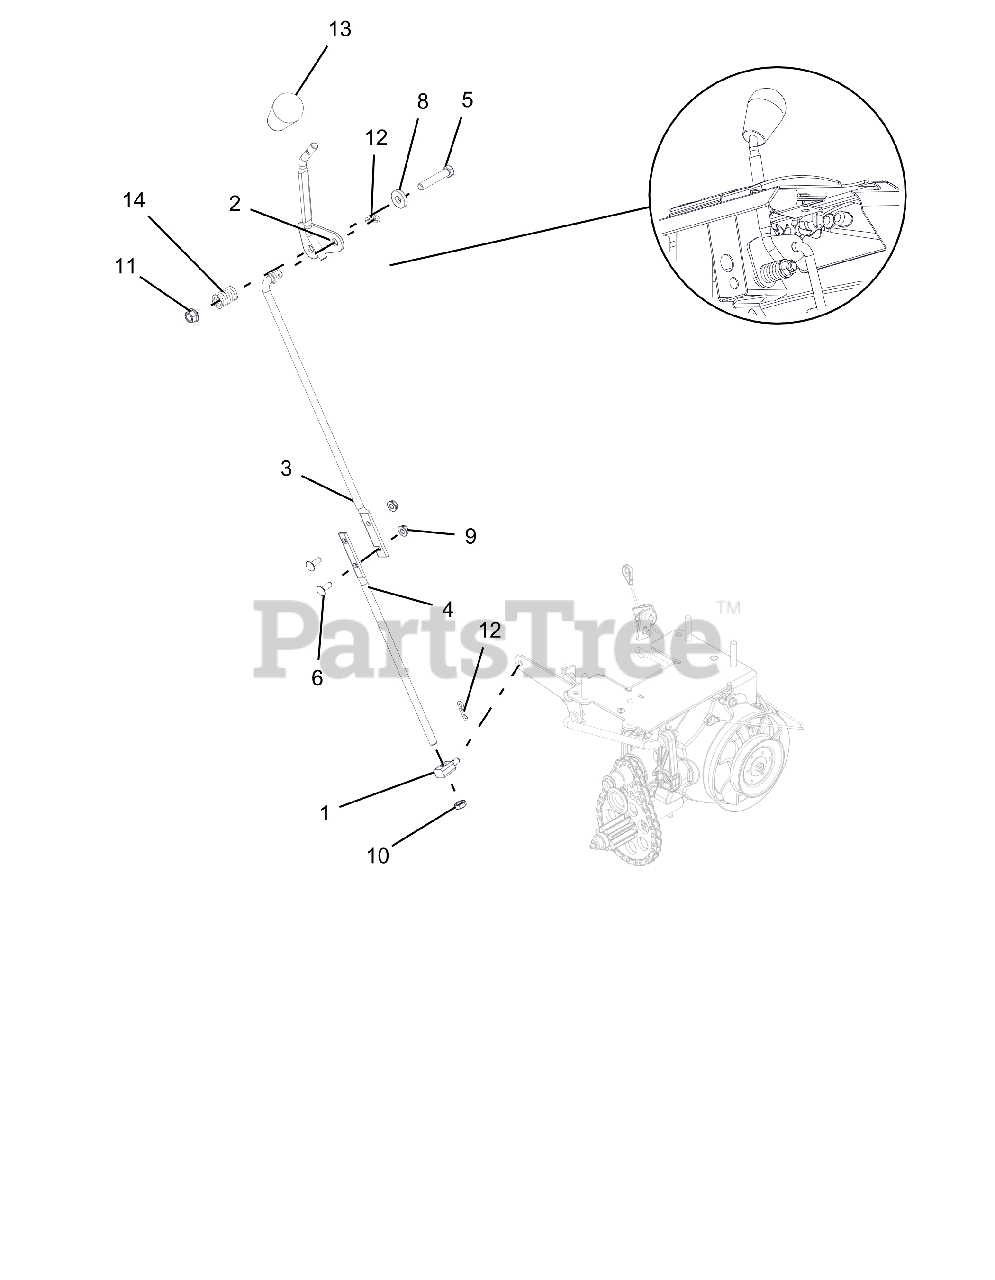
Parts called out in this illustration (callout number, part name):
1	PIVOT, SHIFT ROD .375-16
2	WLDMT, CONTROL LEVER
3	ROD, SHIFT - UPPER
4	ROD, HYDRO SHIFT - LOWER
5	BLT-HEX .38-16X2.00 GR5 YWZC
6	BLT-RDHDSQNK .25-20X.75 G5 YWZC
8	WSHR-FL-STL .406X1.00X.188 YWZC
9	NUT, LK-CTR-FLG .25-20 YWZC
10	NUT, JAM .375-16 YWZC
11	NUT, LK-TOP-FLG .38-16 YWZC
12	PIN, HAIR INT .08X.18X1.18 YWZC
13	KNOB, SOFT TEARDROP, PUSH-ON GRY
14	SPRG, COMPRESSION
